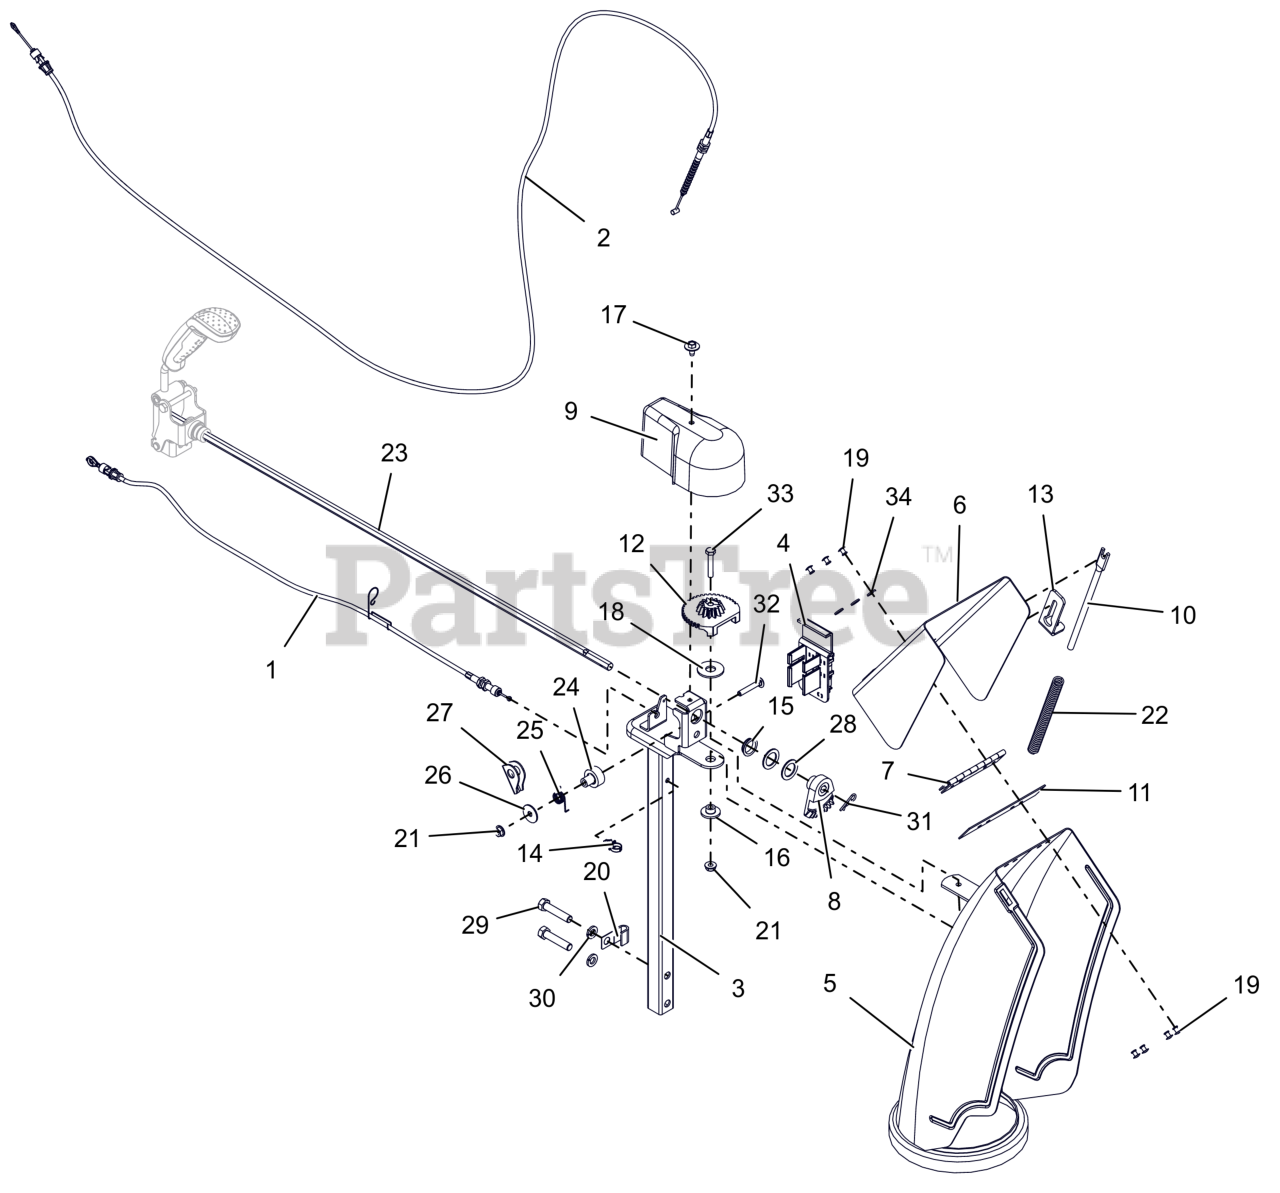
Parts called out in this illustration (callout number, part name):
1	CABLE, CHUTE LOCK, PRO
2	CABLE, DEFLECTOR - DELUXE
3	PEDESTAL, CHUTE - QUICK STICK
4	HOLDER W LARGE SHEAR BOLT /NUT
5	CHUTE,DISCHARGE,NOTCHED,QT
6	CAP, LARGE REMOTE W/DECAL
8	GEAR, CHUTE-ACTUATION
9	COVER, CHUTE GEAR
10	ROD, DEFLECTOR CAP
11	CAP SEAL 5.50
12	GEAR, CHUTE
13	BRACKET, ANCHOR-CHUTE CABLE
14	CLIP, CABLE GUIDE
15	BUSHING, POLYLINER-.75 SNAPIN
16	BSHG-FLG .265X.477X.375X1.00
17	SCR, TAP .25-20X.50 LG HWH ZCC
18	WSHR-FLT-NYL .515X1.375X.093
19	RVT, POP .1875 ZCC
20	J-CLAMP
21	NUT-LK-CTR-FLG .25-20 ZC120
22	SG-COMP .08X.40X6.50 14#/IN
23	ROD, HEX - CHUTE ROTATION
24	BUSHING, LOCK ARM
25	SG-TORS
26	WSHR,FLT .281X1.000X.063 ZCC
27	ARM, LOCKING
28	WSHR, FLT .754X1.125X.062 ZCC
29	BLT, HEX .38-16X1.75 G5 ZCC
30	WSHR,LK-REG .375X.094 ZCC
31	PIN, HAIR #213 .08X1.19 ZCC
32	BLT, RHSN .25-20X1.50 G5 ZCC
33	BLT, HEX .25-20X1.50 G5 ZCC
34	WSHR,FLT .196X.500X.066 ZCC
